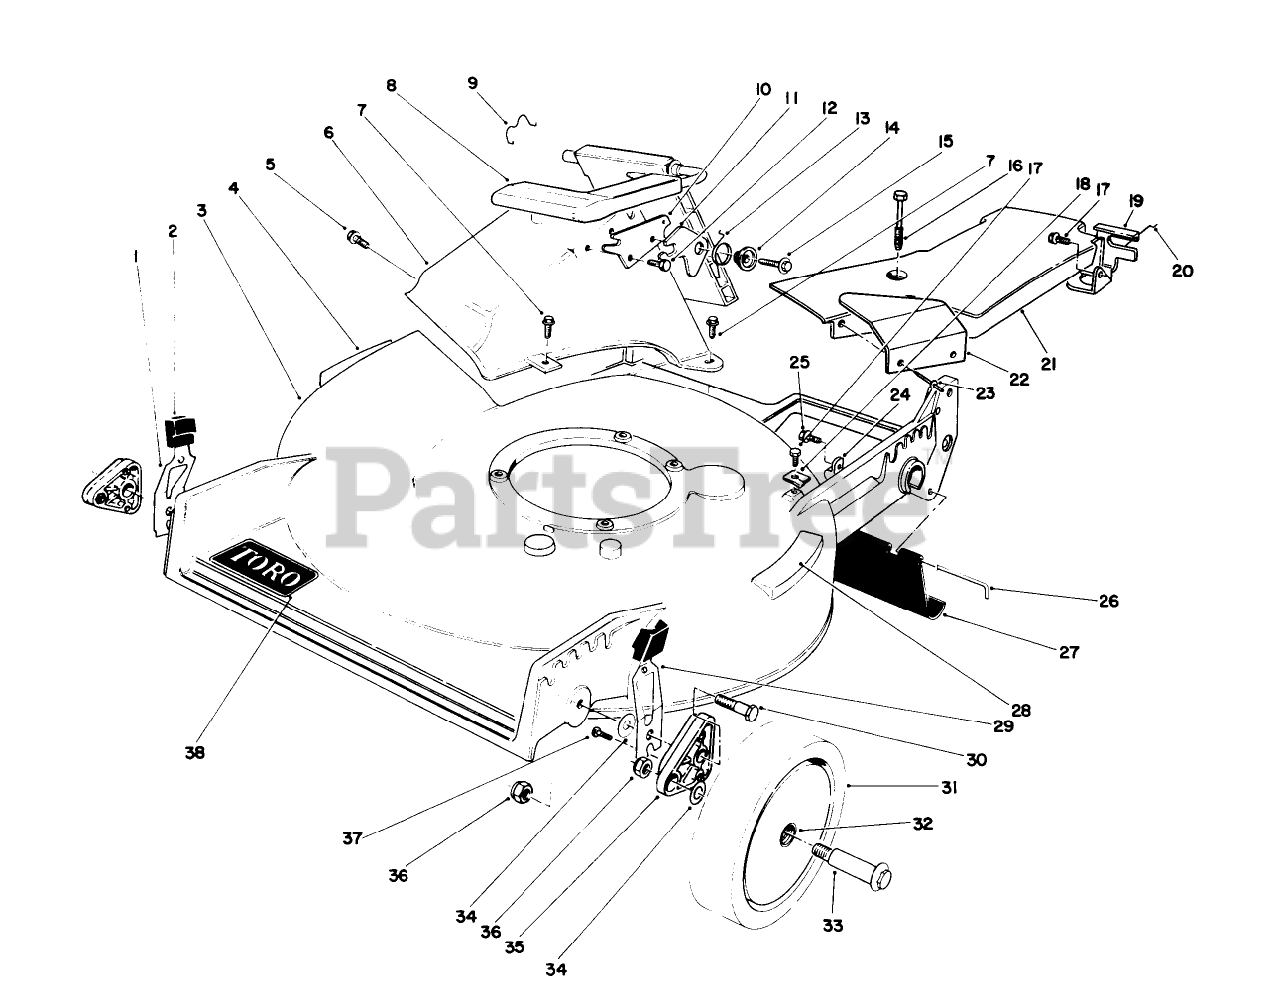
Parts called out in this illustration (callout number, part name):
1	RH SPRING ARM ASSEMBLY
2	KNOB-ARM
3	Housing Assembly (Incl. Ref. #4, 7, & 28)
4	DECAL-DANGER
5	SCREW AND WASHER ASM
6	Tunnel-Discharge
7	SCREW-HWH
8	Discharge Door Assembly
9	DOOR RET SPRING
10	DOOR LATCH PLATE
11	SAFETY LATCH
12	SCREW-PLASTITE
13	TORSION SPRING
14	DOOR SPACER
15	SCREW-HWH
16	SCREW-HHFTF
17	SCREW-HWHTF
18	CLAMP-CABLE
19	Bracket-Traction Adj.
20	RETAINER-CABLE
21	BELT COVER ASM
22	HEAT SHIELD
23	RIVET-HEAD, FLAT
24	CLAMP-CABLE
25	SCREW
26	ROD-SHIELD
27	SHIELD-TRAILING
28	STEP PAD DECAL
29	LH SPRING ARM ASSEMBLY
30	SCREW-SHOULDER
31	Wheel & Tire Assembly (Incl. Ref. #32)
32	BUSHING
33	WHEEL BOLT
34	WASHER
35	ARM-PIVOT, FRONT
36	Nut
37	SCREW-HWH
38	DECAL
